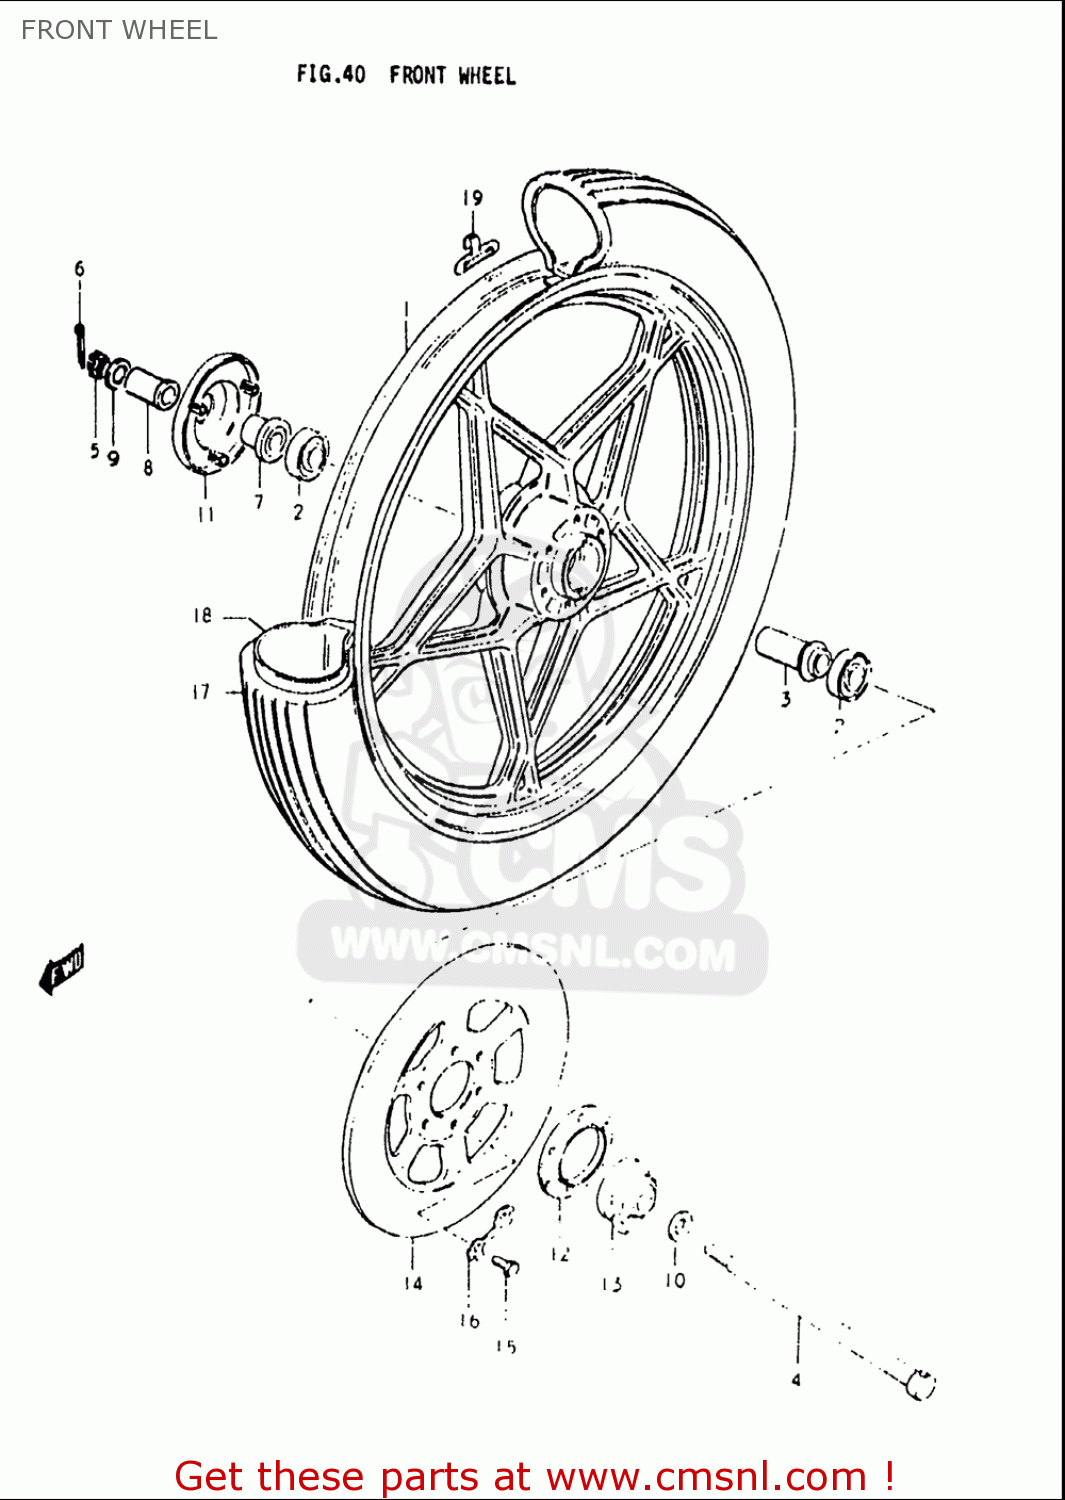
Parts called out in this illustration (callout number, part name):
1	WHEEL,FR(19XMT1.85)
2	B1 15X42X13 BEA
3	SPACER,FR HUB BEARING
4	AXLE,FR
5	NUT 12MM
6	PIN
7	SPACER,FR AXLE,R
8	SPACER
9	WASHER
10	WASHER(15.5X26X2.3)
11	COVER,FR HUB,R
12	DUST SEAL,SPEEDOMETER GEAR BOX
13	BOX ASSY,SPEEDOMETER GEAR
15	BOLT(8X25)
16	WASHER(8.5X20X1.6)
18	TUBE ASSEMBLY,WHEEL,INNER
19	BALANCER,WHEEL
